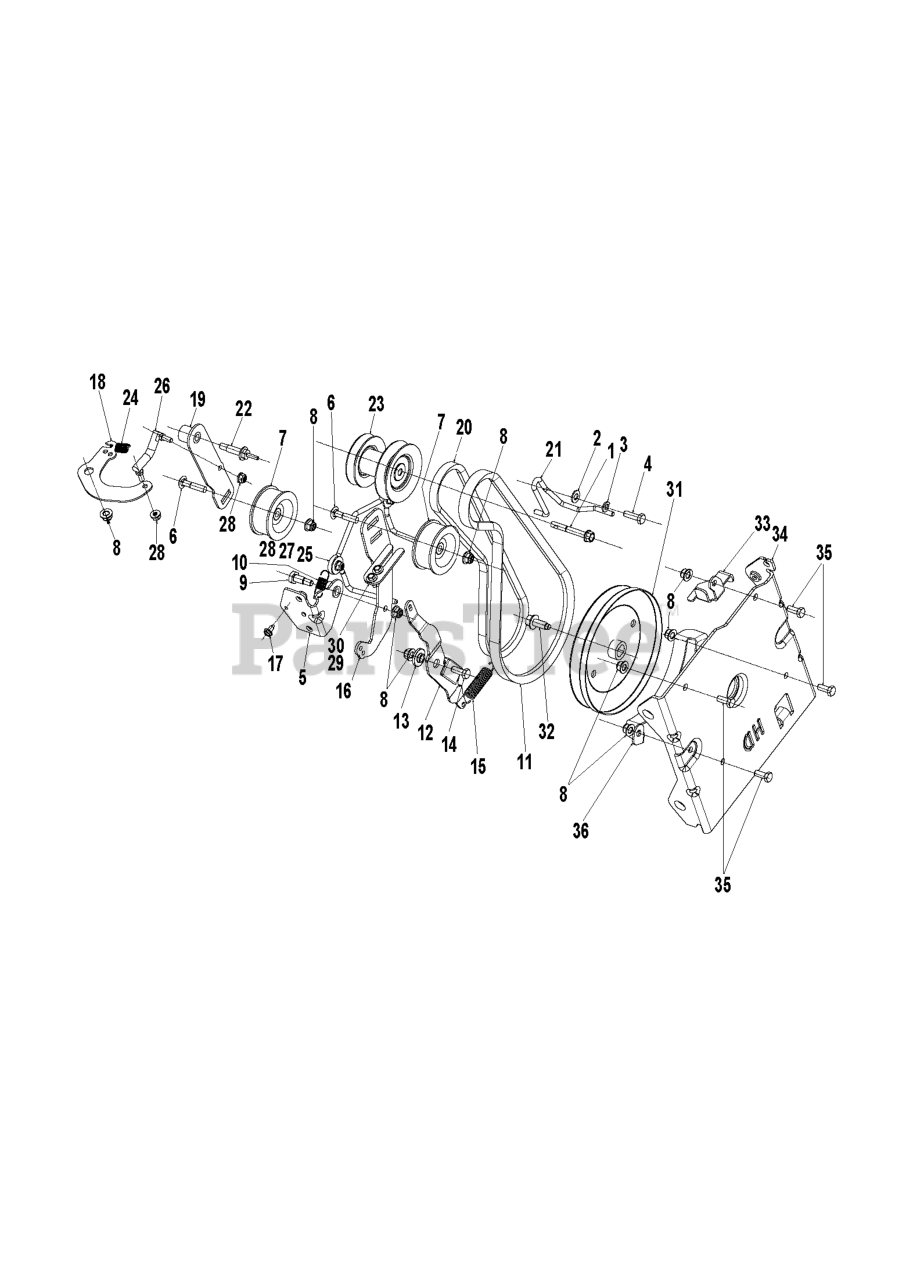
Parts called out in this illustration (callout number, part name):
2	WASHER 11/32 X 11/16 X 14 GA T
3	WASHER SPRING LOCK WASHER WITH
5	BRACKET WELDMENT, IDLER ARM ZI
6	BOLT 5/16-18 CARRIAGE 1.5L
8	NUT HEXAGON FLANGE 5/16-18 ST
10	SPRING IDLER RETURN
11	BELT 5L 39.15L
12	ARM IMPELLER BRAKE
13	BUSHING.BRAKE.ARM
14	BOLT HEXAGON BOLT 5/16-18 X 7/
15	SPRING EXTENSION - BRAKE
16	ARM IDLER BLACK ZINC
18	Bell Cranks
19	ARM DRIVE IDLER BLACK ZINC PLA
20	BELT 4L DRIVE
21	Belt Keepers
22	GUIDE BELT, SHOULDER SCREW
23	PULLEY 5L HYDRO
24	SPRING EXTENSION - DRIVE
25	GUIDE BELT - HYDRO 2 WITH FAN
26	LINK ASSY DRIVE IDLER
28	NUT FLG, NYLOCK, 1/4-20 GR G C
30	HEX.WASHER.HEAD 1/4-20 X .65
31	PULLEY IMPELLER DD 5L HD
32	SCREW HEXAGON HEAD FLANGE 3/8-
34	BRACKET AUGER HOUSING INTERFAC
35	SCREW HEXAGON HEAD SCREW 5/16-
36	BRACKET.BELT.KEEPER.LOWER.BLAC
